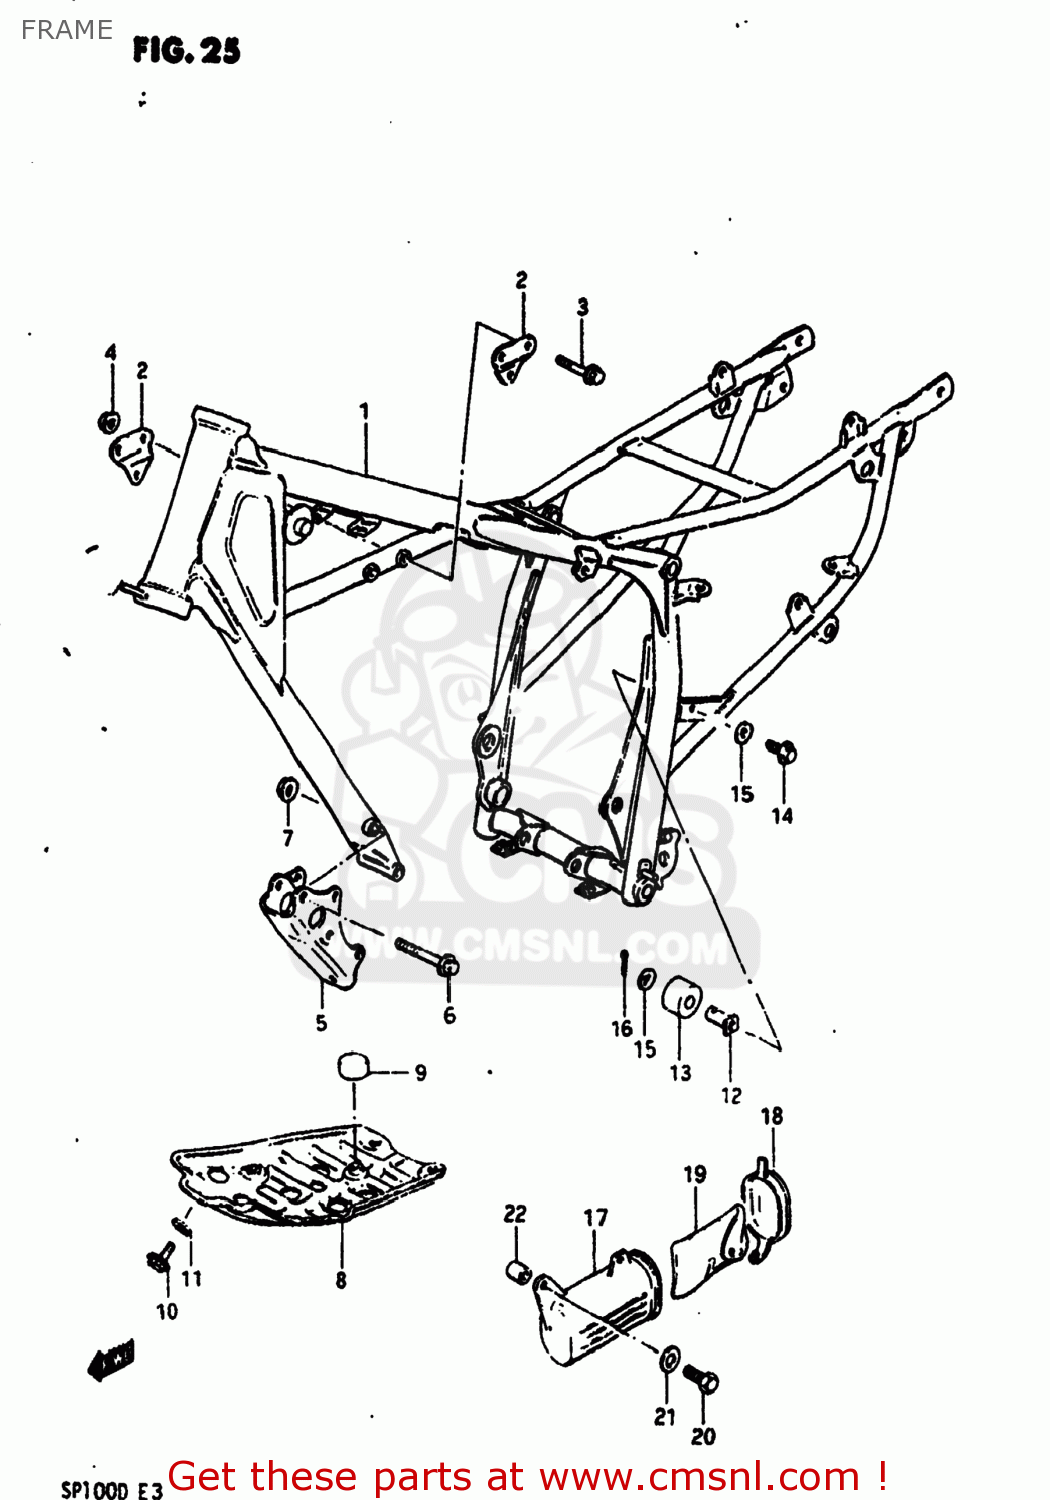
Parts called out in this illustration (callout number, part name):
1	FRAME
2	PLATE,ENGINE MOUNTING
3	BOLT(8X50)
4	NUT
5	PLATE,ENGINE MOUNTING
6	BOLT 8X67
7	NUT
8	PROTECTOR,ENGINE
9	CUSHION
10	BOLT
11	WASHER
12	BOSS,CHAIN CONTROL
13	ROLLER,CHAIN LENGTH CONTROLLER
14	BOLT
15	WASHER
16	PIN 25X20
17	HOLDER,TOOL
18	CAP,HOLDER
19	TOOL SET
20	BOLT, UPPER
21	WASHER (6.5X18X1.6)
22	SPACER (8.8X12X4)
